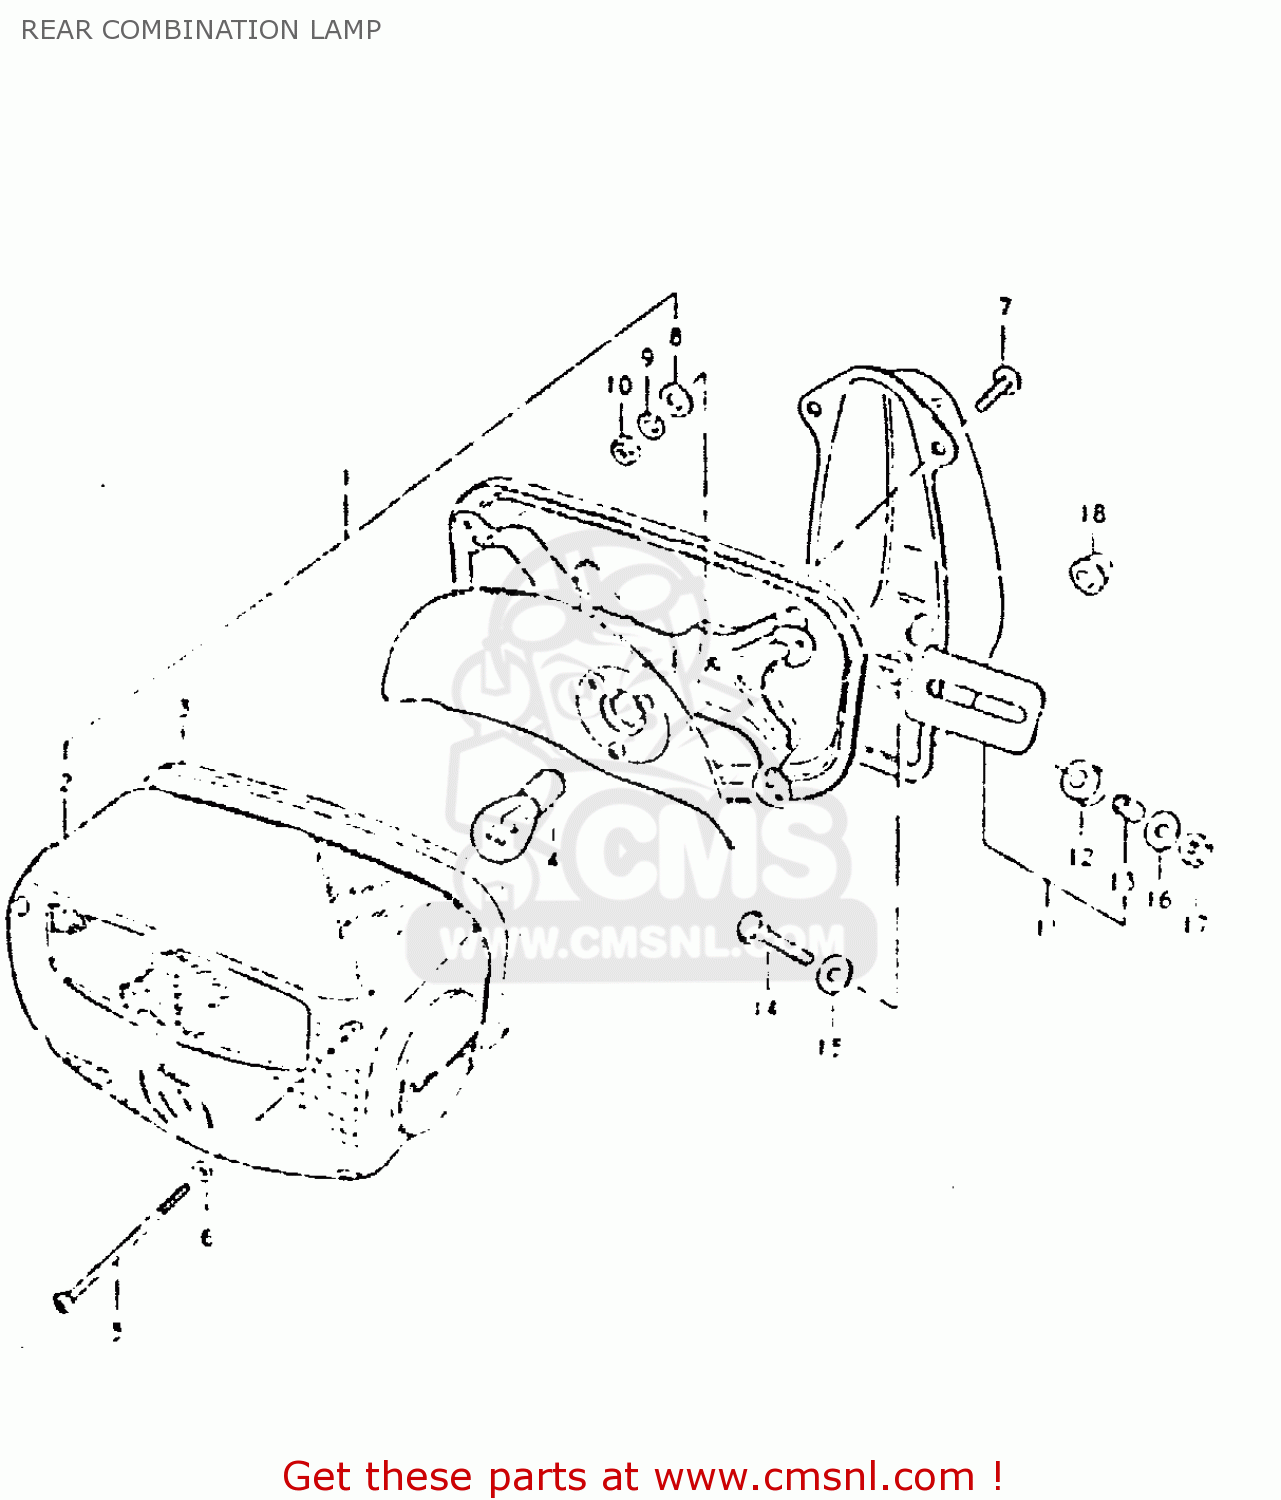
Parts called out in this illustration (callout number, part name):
1	LAMP UNIT, TAIL
2	LENS,REAR COMBINATION LAMP
3	GASKET (NAS)
4	BULB 12V21/5W
5	SCREW (4X55)
6	GASKET (NAS)
7	SCREW 6X12
8	WASHER
9	LOCK WASHER
10	NUT
11	BRACKET ASSY
12	CUSHION
13	SPACER
14	BOLT
15	WASHER (6.5X20X1.2)
16	WASHER
17	NUT
18	GROMMET
